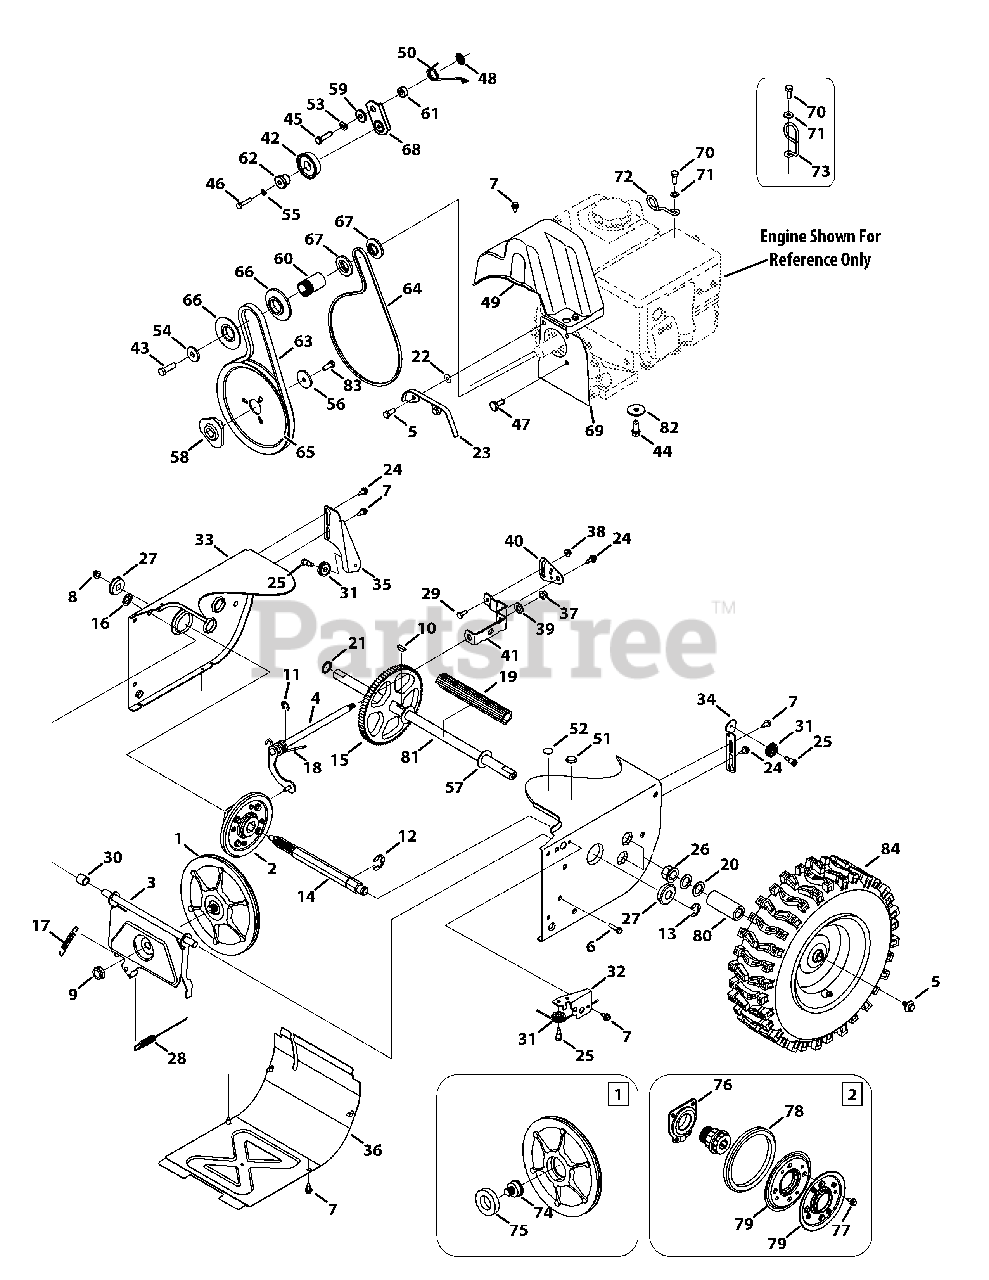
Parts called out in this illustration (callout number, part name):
1	Disc Assembly, Friction Wheel
2	Friction Wheel Assembly, 5.5 OD
3	Friction Wheel Support Bracket
4	Rod Shift Assembly
5	Screw, 5/16-24 x .750
6	Taptite Screw, 1/4-20 x 1.000
7	Taptite Screw, 1/4-20 x .625
8	Flange Lock Nut, 3/8-16
9	Flange Nut, 5/8-18
10	Hi-pro Key, 3/16 x 3/4 Dia.
12	Retaining E-Ring, .875 Dia.
13	E-Ring, .750 Dia.
14	Hex Shaft, 7-Tooth
15	Gear, 80-Tooth
16	Speed Nut, .500
17	Extension Spring
18	Torsion Spring, .750 x .968
19	Axle Spacer
20	Flat Washer, .793 x 1.24 x .060
21	Flat Washer, .75 x 1.00 x .060
22	Washer, Flat, .385 x .62 x .063
23	Belt Cover
24	Shoulder Screw, .368 x .113, 1/4-20
25	Shoulder Screw, 1/4-28, .340 x .355
26	Hex Flange Bearing
27	Ball Bearing, 17 x 40 x 12
28	Wheel Clutch Cable, 44.955"
29	Hex Head Screw, 1/4-20 x .620
30	Spacer, .508 ID x .75 OD x .68
31	Cable Roller
32	Auger Cable Front Guide Bracket
33	Frame
34	Auger Cable Guide Bracket
35	Drive Cable Guide Bracket
37	Flange Lock Nut, 5/16-18
38	Flange Lock Nut, 1/4-20
39	Washer, Flat, .469 x .875 x .105
40	Speed Selector Pivot Bracket
41	Speed Selector Shift Bracket
42	Idler Pulley Assembly
43	Hex Screw, 3/8-24 x 1.25
44	Sems Screw, 3/8-16 x 1.00
45	Hex Screw, 5/16-24 x 1.25
46	Hex Screw, 1/4-20 x 1.25
47	Shoulder Screw, 5/16-24 x .5
48	Push-on Nut, .25 Dia.
49	Belt Cover, 4-Way
50	Torsion Spring, .850 ID x .333
51	Plug, 3/8 ID
52	Plug, 1/2 ID
53	Lock Washer, 5/16
54	Flat Washer, .45 x 1.5 x .172
55	Washer, Lock, 1/4
56	Flat Washer, .34 x 1.50 x .150
57	Washer, Flat, .760 x 1.49 x .060
58	Adapter Pulley, .75 Dia.
59	Shoulder Spacer, .3175 x .5 x .0975
60	Spacer, .875 ID x 1.185 OD
61	Spacer, .340 x .750 x .330
62	Shoulder Space, .260 x .785 x .538
63	Auger Drive Belt, Standard
64	Wheel Drive Belt, Standard
65	Auger Drive Pulley, 8.1 x .5
66	Pulley Half, 2.600 OD
67	Pulley Half, 3/8 x 1.716 OD
68	Wheel Drive Idler Bracket
69	Cover Plate, Standard
70	Hex Head Screw, 1.25 x 20
71	Washer, Flat, .330 x .630 x .0635
72	Cable Guide
73	Cable Guide
74	Friction Disc Bearing Pin
75	Ball Bearing, 30 x 55 x 13
76	Bearing Assembly
77	Taptite Screw, 5/16-18 x .750
78	Friction Wheel Rubber
79	Friction Wheel Plate
80	Spacer, 1.25 x .75 x 3.0
81	Axle, .75 x 22
82	Washer, Flat, .38 x 1.38 x .125
83	Hex Head Screw, 5/16-24 x .875
84	X-Trac Wheel, 15 x 5 x 6, LH
84	X-Trac Wheel, 15 x 5 x 6, RH
